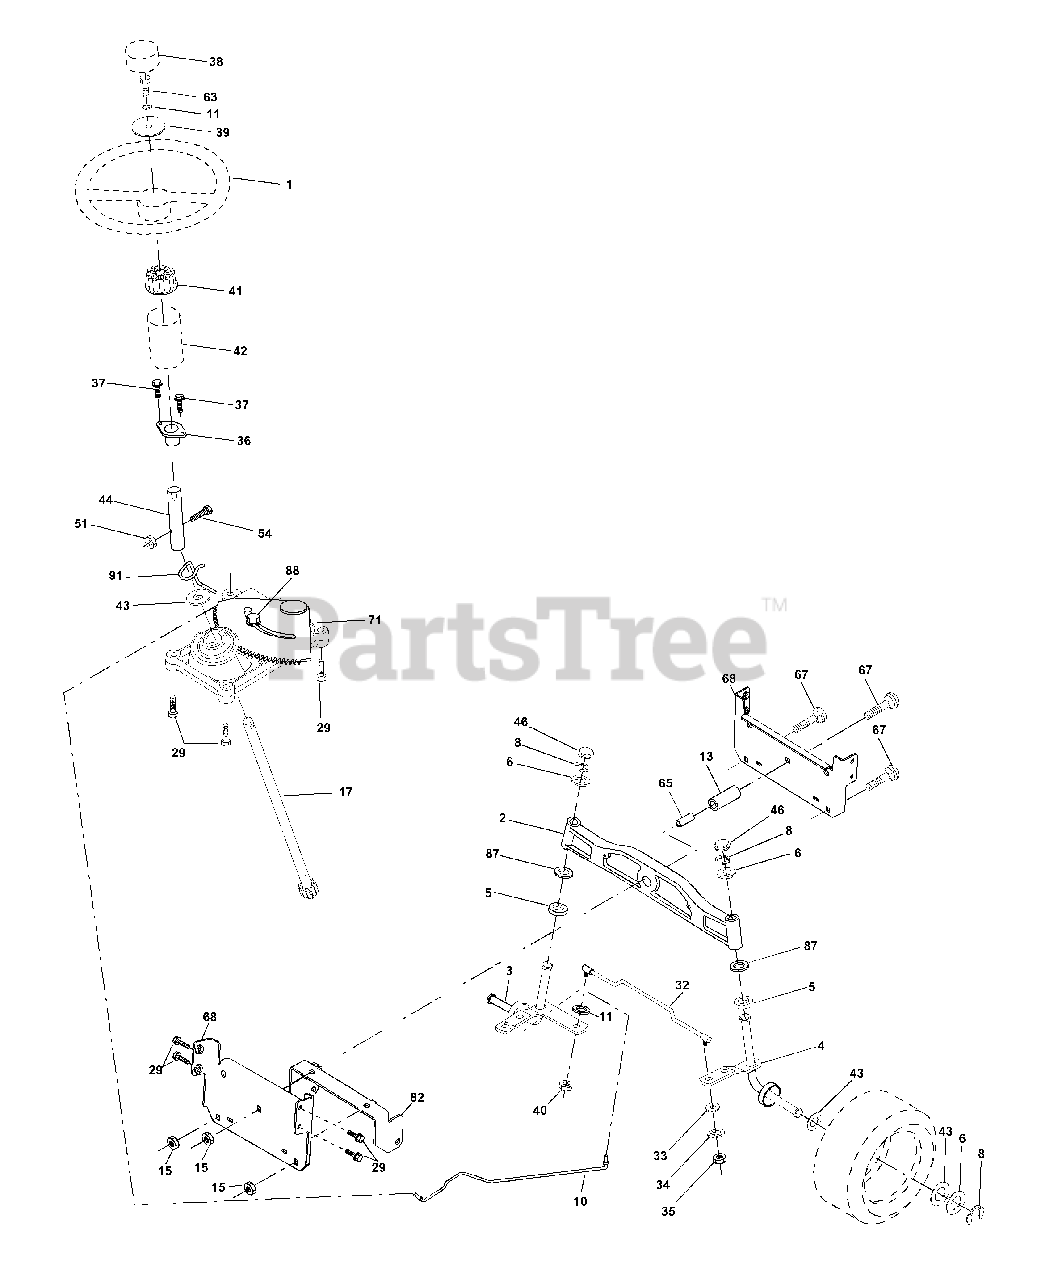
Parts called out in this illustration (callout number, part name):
1	Wheel Steering
2	Axle Asm Cast Iron LT
3	Spindle Asm LH
4	Spindle Asm RH
5	Bearing Race Thrust Harden
6	Washer 25/32 X 1-5/8 X 16 Ga
8	Ring Klip #t5304-75
10	Link Drag
11	Washer Lock Hvy Hlcl Spr 3/8
13	Spacer Brg Axle Front
15	Nut Hex Flange Lock
17	Shaft Asm Strg
29	Screw 3/8-16 x .75
32	Rod Tie
33	Washer 11/32 x 3/4 x 16 Ga
34	Washer Lock Hvy Hlcl Spr 5/16
35	Crownlock Nut 5/16-24 Unf
36	Bushing Strg
37	Screw
38	Insert Cap Strg Wh
39	Washer 13/32 X 1-1/2 X 11 Ga
40	Lock nut
41	Adaptor Wheel Strg
42	Boot Steering Dash
43	Washer 25/32 X 1 1/4 X 16 Ga
44	Extension Steering Shaft LR/LT
46	Cap Spindle Fr Top Blk
51	Nut Lock Hex w/Ins 5/16-18
54	Bolt Fin Hex 5/16-18 Unc x 1-1/4
63	Bolt Fin Hex 3/8-16unc x 1 Gr. 5
65	Spacer Brace Axle
67	Bolt Rdhd Sq 3/8-16 Unc x 2-3/4
68	Axle, Brace
71	Steering Asm
82	Bracket Susp Chassis Front
87	Washer Flat .781 x 1-1/2 x .14
88	Boult Shoulder 7/6-20
91	Clip Steering
